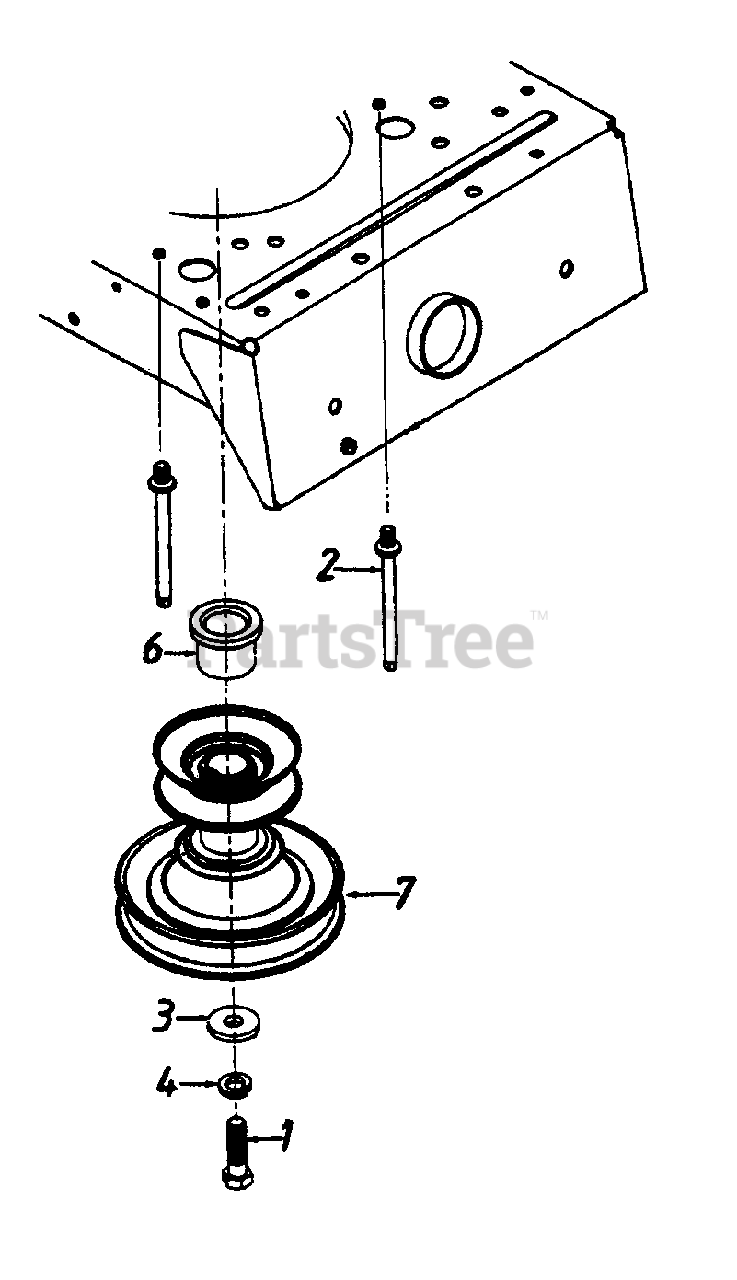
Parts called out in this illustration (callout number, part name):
1	Hex Bolt 7/16-20 x 1.5" Lg.
2	Belt Guard Stud 4.75" Lg.
3	FL-Wash. 7/16" I.D. x 1.25" O.D.
4	L-Wash. 7/16" I.D.
6	Spacer
7	Engine Pulley
